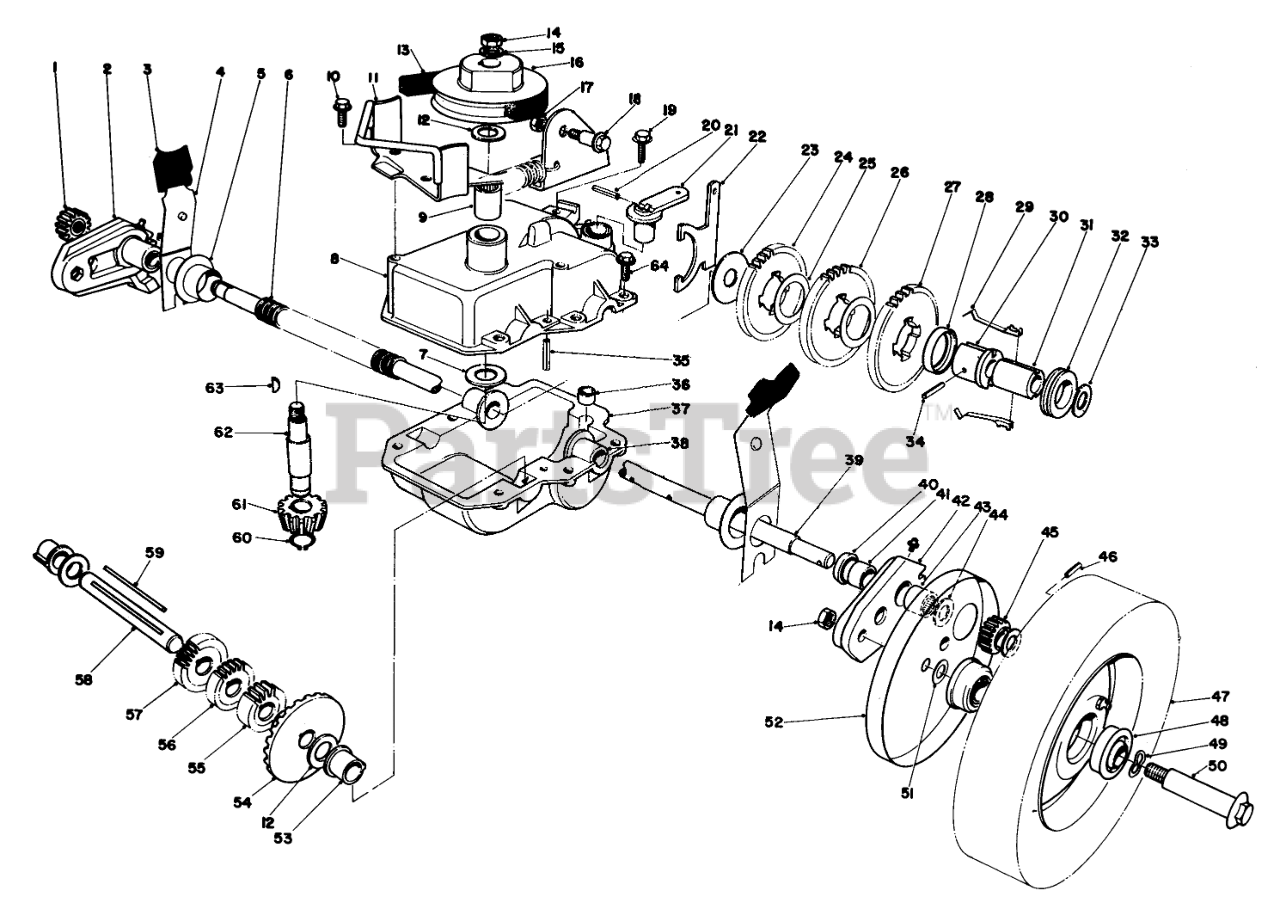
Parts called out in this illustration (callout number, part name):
1	RH CLUTCH & PINION
2	Pivot Arm R.H. (Incl. Ref. #40-43)
3	KNOB-ARM
4	Spring Arm
5	CAP-END
6	CONDUIT-CONVOLUTED, SPLIT
7	Thrust Washer
8	Case-Upper
9	Bearing
10	Screw
11	Belt Guide Bracket
12	WASHER-THRUST
13	V-BELT
14	Nut
15	WASHER-FLAT
16	Pulley
17	NUT-HEX, SIDE DEFORM
18	Shoulder Bolt
19	SCREW-HWHTF
20	PIN-COIL
21	LEVER-SHIFT
22	Shift Yoke
23	WASHER
24	Gear 35 Tooth
25	WASHER
26	Gear 37 Tooth
27	GEAR-42T
28	KEY RETAINER
29	Key
30	Body-Sleeve
31	SLEEVE
32	COLLAR-SHIFT
33	WASHER-PLAIN
34	PIN-SPRING
35	ROLL PIN 3/16 X 1 IN
36	BUSHING-YOKE
37	LOWER GEAR CASE CAST
38	Bushing
39	OUTPUT SHAFT
40	Seal
41	Bushing
42	Pivot Arm L.H. (Incl. Ref. #40, 41, & 43)
43	Needle Baring
44	WASHER
45	LH CLUTCH & PINION
46	Pin
47	Wheel & Tire Assy. (Incl. Ref. #48)
48	BEARING-BALL
49	SPRING WASHER
50	WHEEL BOLT
51	WASHER
52	Cover-Wheel
53	Botching Shaft
54	BEVEL GEAR
55	14 T GEAR
56	Gear 19 Tooth
57	Gear 21 Tooth
58	Sort Shaft
59	Key Square
60	RING-RETAINING
61	PINION-BEVEL
62	INPUT SHAFT
63	KEY-WOODRUFF
64	SCREW-HWH, THREAD ROLL
